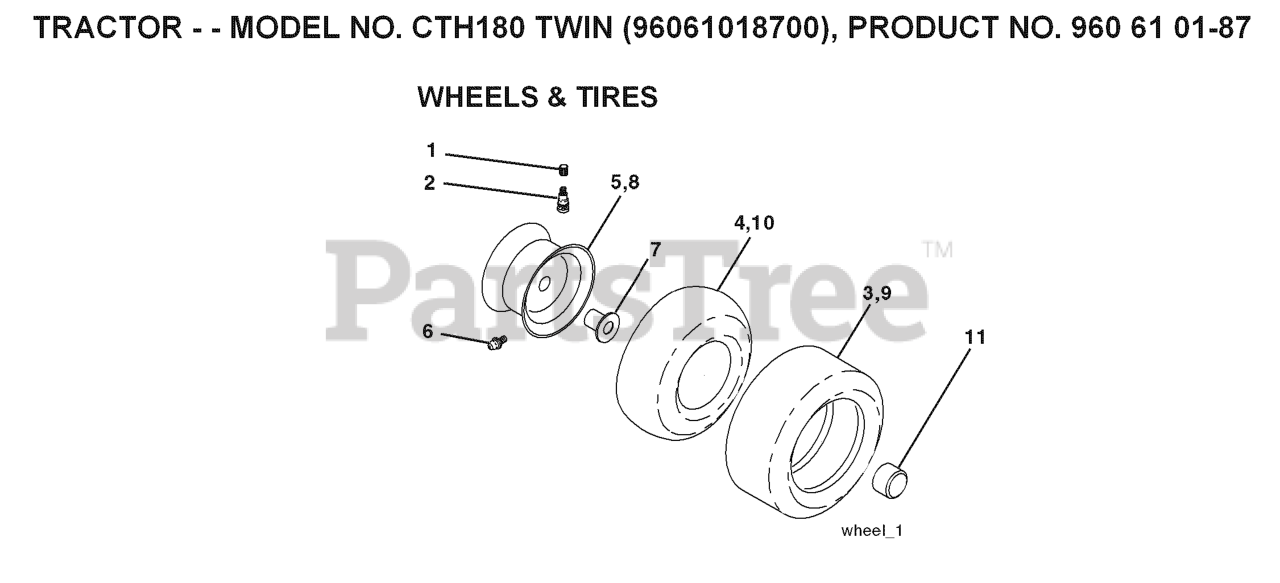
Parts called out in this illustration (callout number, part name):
2	VALVE STEM LT
3	TIRE HEAVY DUTY
4	TUBE.5.3/4.5/6
5	RIM ASM 6" FRONT SILVER
6	FITTING LT
7	BEARING T
8	RIM ASM 8" REAR SILVER
9	TIRE.TS.20X10-8
10	TUBE
11	CAP, AXLE BLK
